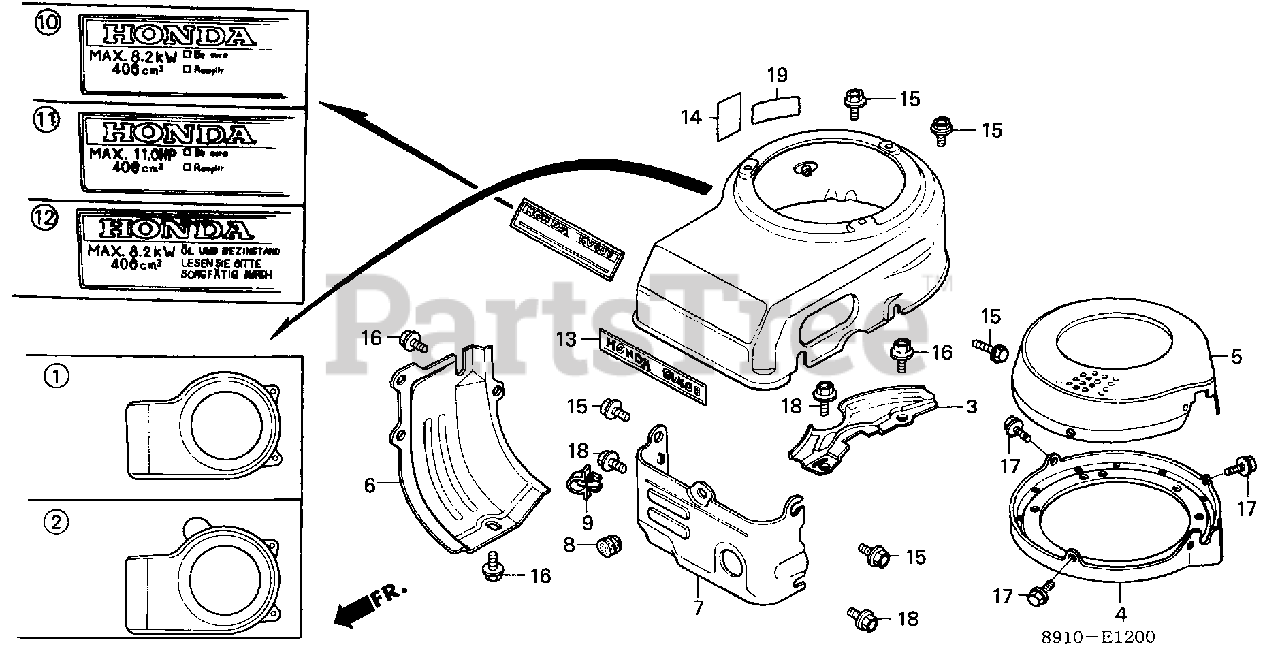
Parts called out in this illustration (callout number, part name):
3	PLATE, SIDE
7	COVER, TOP
8	GROMMET, TOP COVER
9	CLIP, IGNITION WIRE (8MM)
14	MARK, OIL CAUTION
15	BOLT, FLANGE (6X12) (CT200)
16	BOLT, FLANGE (6X16)
18	BOLT, FLANGE (6X12)
